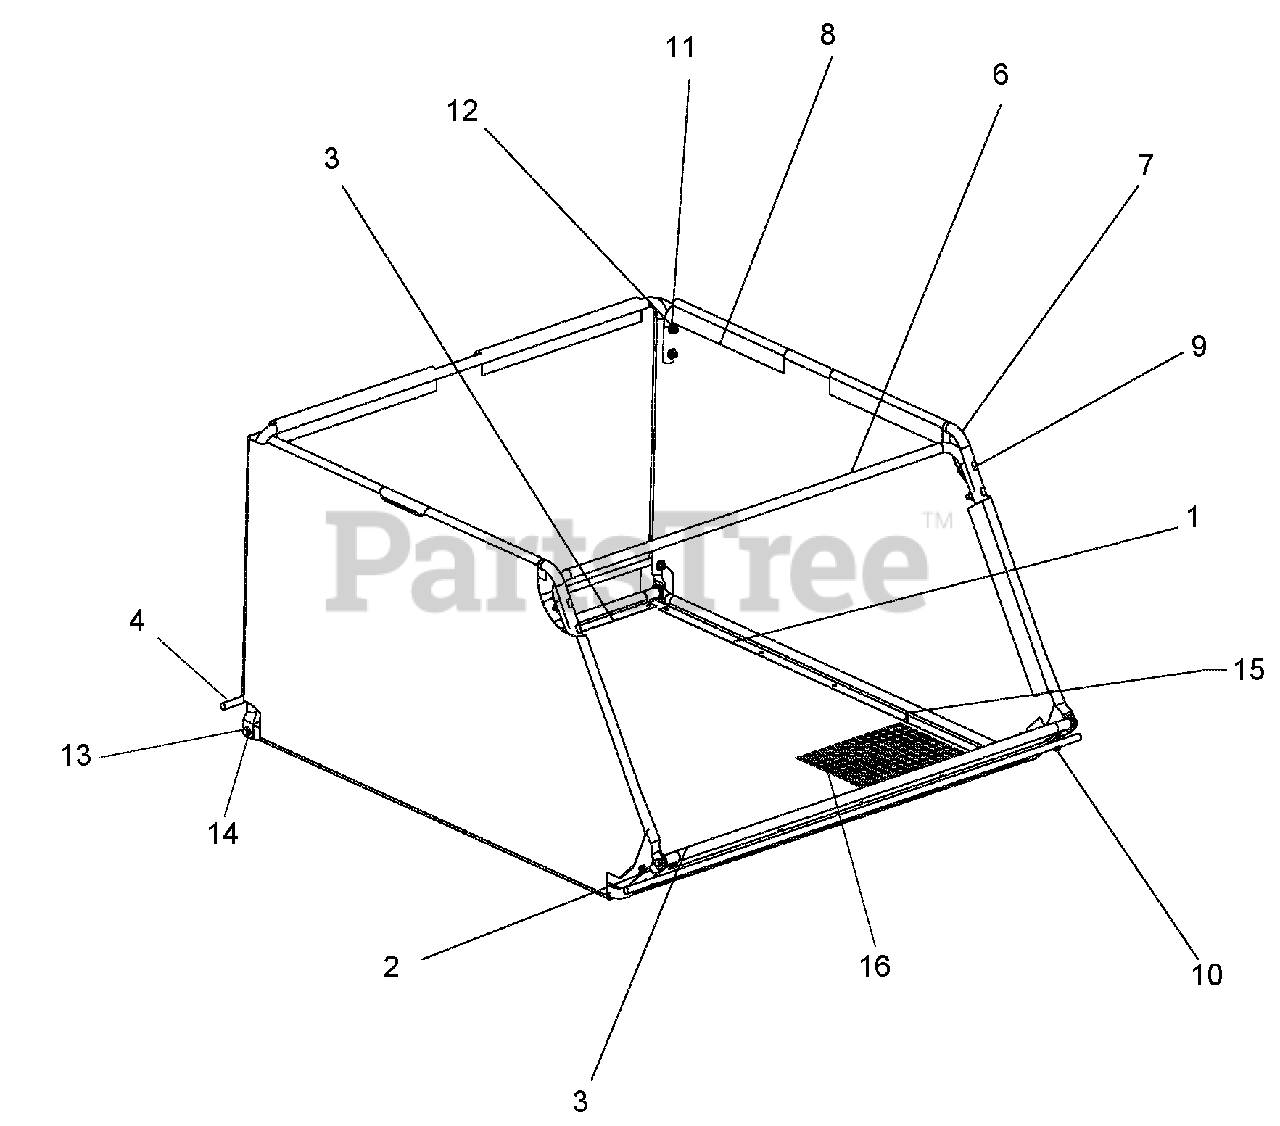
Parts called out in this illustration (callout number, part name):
1	Basket Clamp Assembly
2	Basket Clamp Assembly
3	Basket Clamp Assembly
4	Support Rod
5	Rear Upright
6	Front Upright
7	Frame Basket Side Top
8	Basket Assembly
9	Bolt, 1/4-20 x 2.0 Contour Hd.
10	Bolt, Hex .25-20X1.50
11	Washer, Flat Steel .312X.734X.065
12	Nut, Hex, 1/4-20 YWZC
13	Lockwasher .31X.078
14	Bolt, Hex .31-18X1.00
15	Rivet, Bulb Tite
16	Basket Bottom, Mesh
17	Basket Bottom, Solid
